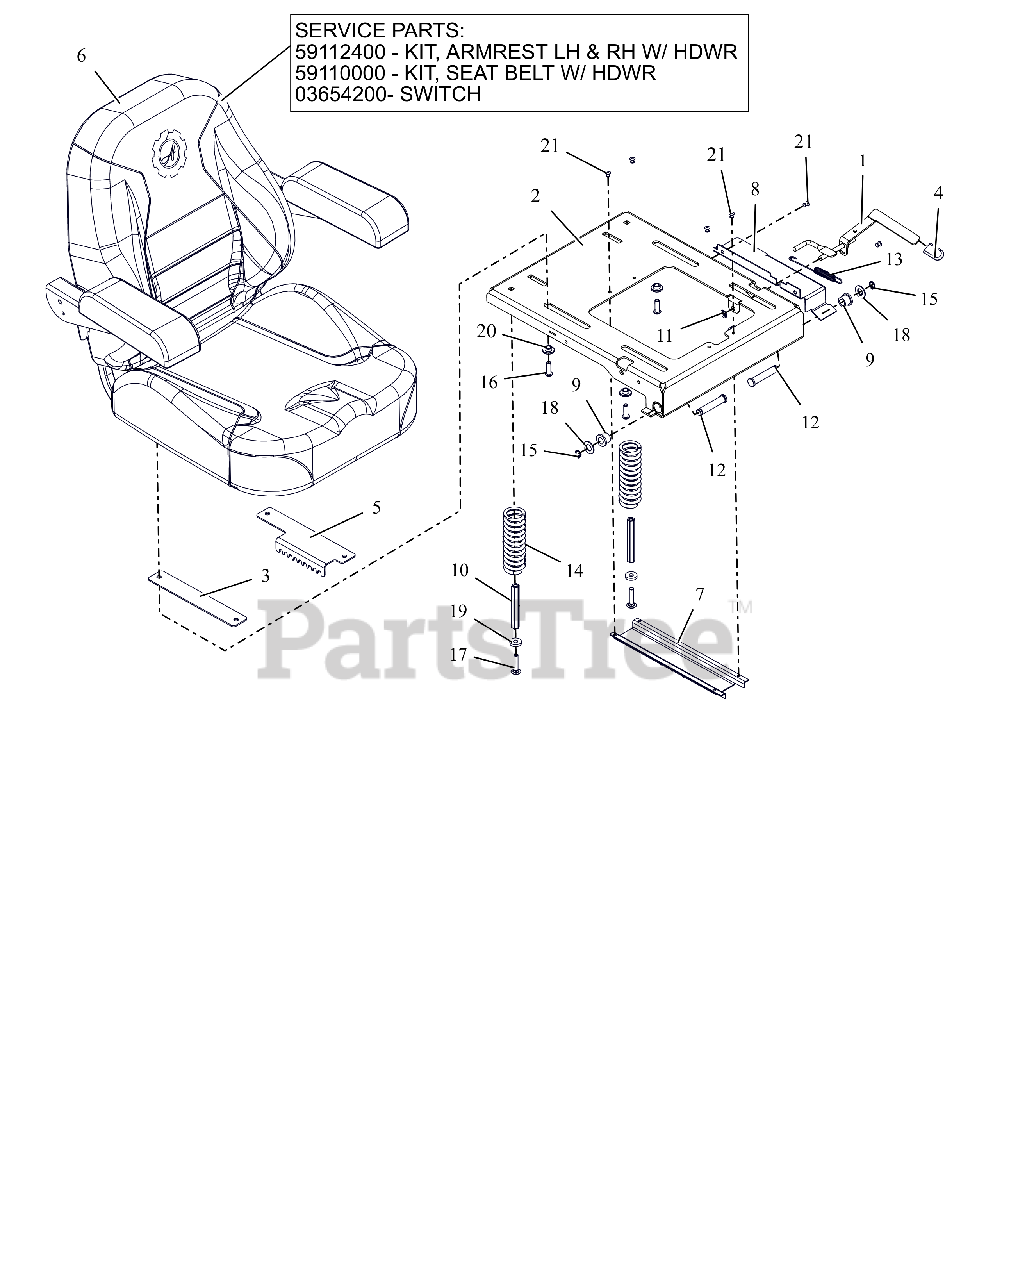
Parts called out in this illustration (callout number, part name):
1	WLDMT, SEAT SLIDE LEVER
2	WLDMT, SEAT PLATE HD
3	PLATE, ADJUSTABLE SEAT SLIDE
4	GRIP, SEAT LEVER, GREY
5	PLATE, HD SEAT ADJUSTMENT
6	SEAT, APEX
6	KIT-LH & RH ARM REST-05124700
6	KIT-SEAT BELT REPLACE-05007300
6	SWITCH- SEAT
7	GUARD,SEAT SWITCH
8	GUARD, SEAT PLATE CE
9	BSHG, FLG .516X.750X.625X.937
10	NUT, COUPLING 5/16X18 X 3.75
11	NUT-PUSH .312
12	PIN, SEAT PIVOT -.500X2.31
13	SG-TENS .06X.482X5.35
14	SPRING, COMPRESSION SEAT 224LB
15	RG-RTNG-EXT .500X.050 (SNAP)
16	BLT,SHCS-BTN .31-18X1.00 ZCC
17	BLT,RHSN .31-18X1.50 G5 ZCC
18	WSHR, FLT .531X1.00X.063 ZCC
19	WSHR, FLT .328X.870X.179 ZCC
20	BSHG-FLG .32X.500X.344X.880
21	RIVET, .1875 AL/AL .126-.250
